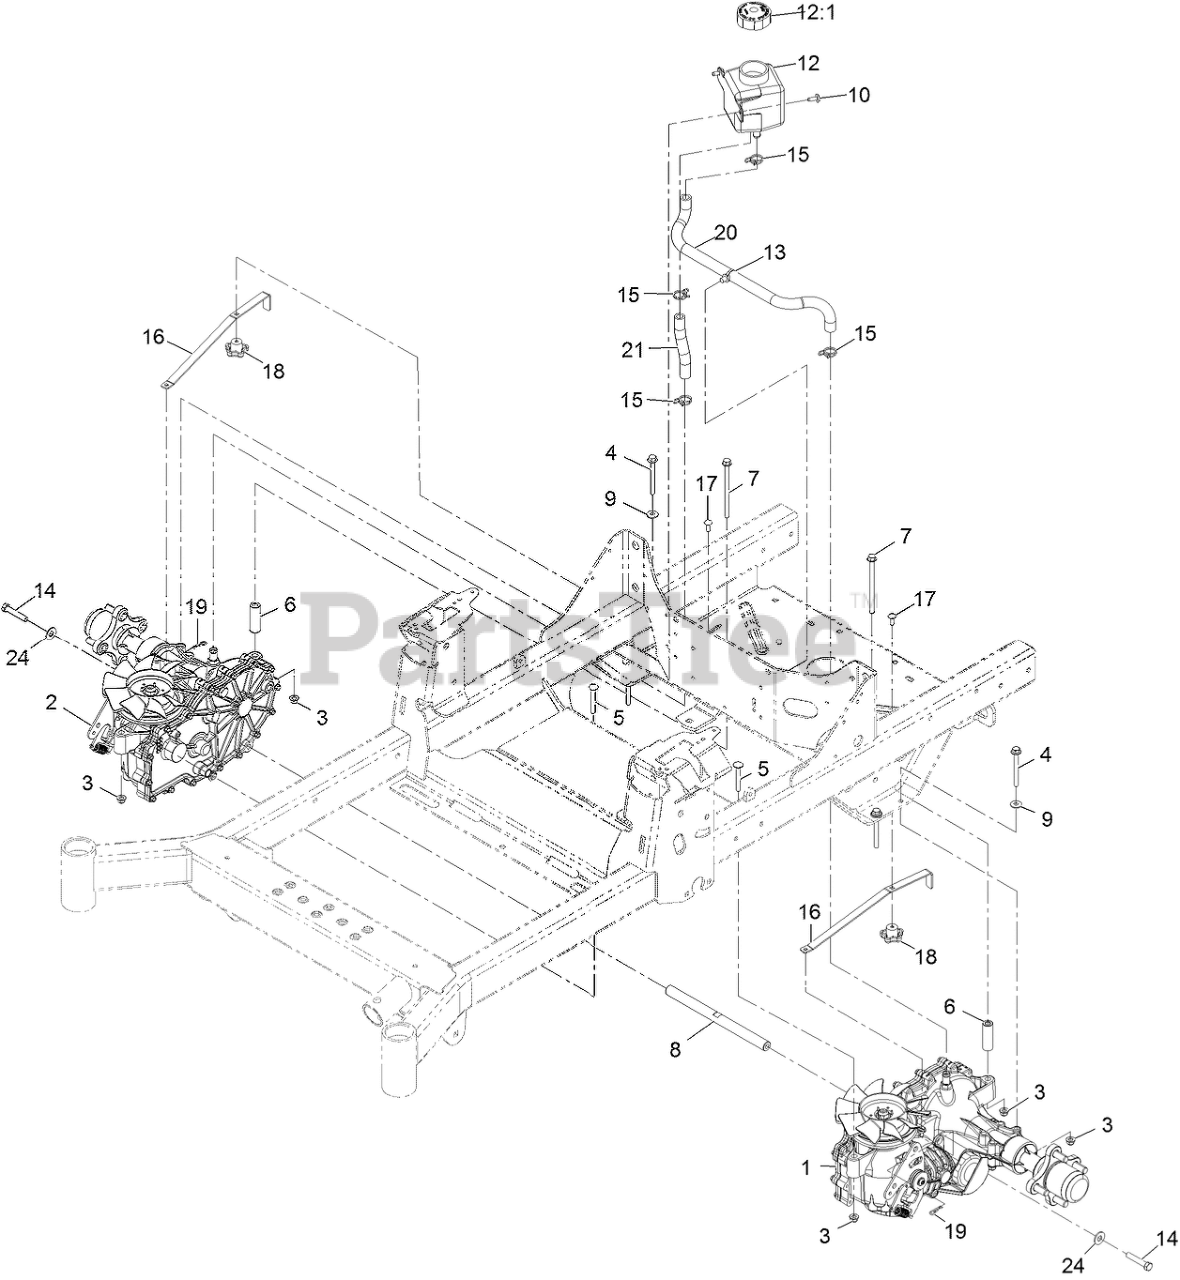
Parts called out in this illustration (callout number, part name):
1	TRANSAXLE ASM LH
2	TRANSAXLE ASM RH
3	NUT-HF, NI
4	SCREW-HHF
5	BOLT-CARR
6	SPACER-HYDRO
7	SCREW HHF
8	SHAFT-SPACER
9	WASHER-SPRING
10	SCREW-TORX
12	TANK-HYD
12:1	CAP-RESERVOIR, HYD
13	CLIP-TIE
14	SCREW-HH W/LOCTITE
15	CLAMP-HOSE
16	ARM-BYPASS, HYDRO
17	BOLT-CARR
18	KNOB-HANDLE
19	PIN-COTTER
20	HOSE-HYDRAULIC
21	HOSE-HYDRAULIC
24	WASHER-FLAT
